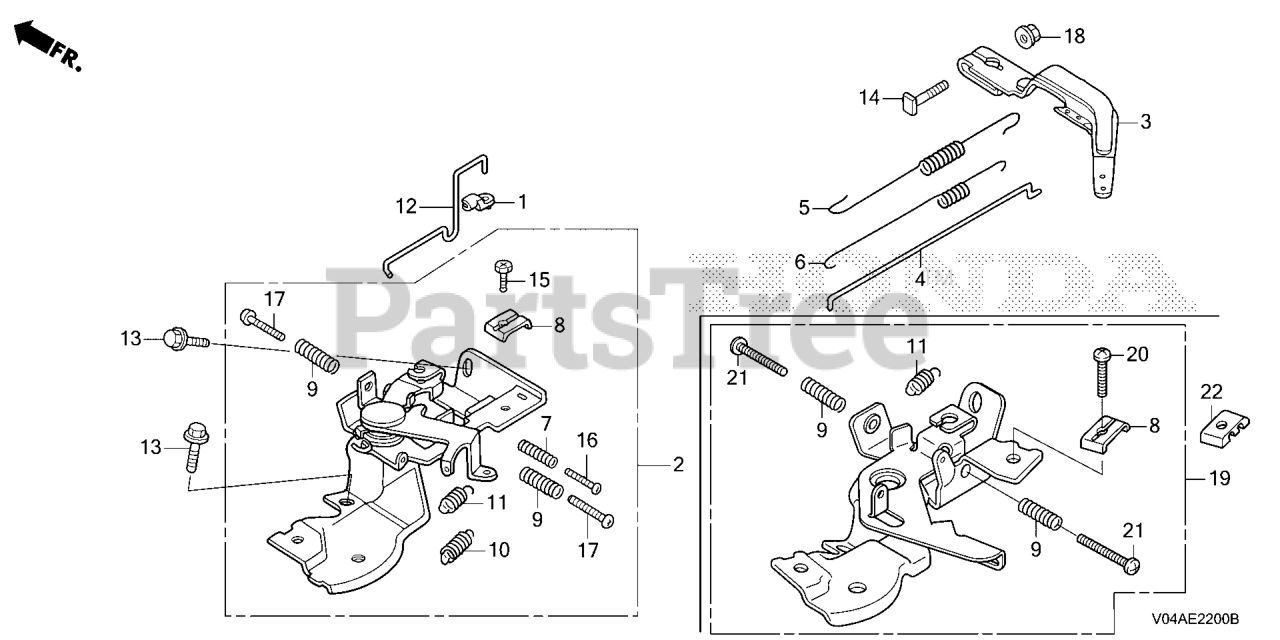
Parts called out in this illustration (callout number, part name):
3	ARM, GOVERNOR
4	ROD, GOVERNOR
5	SPRING, GOVERNOR
6	SPRING, THROTTLE RETURN
8	HOLDER, CABLE
9	SPRING, CONTROL ADJUSTING Use from Engine SN 2327377.
11	SPRING, CABLE RETURN
13	BOLT, FLANGE (6X12) (CT200)
14	BOLT, GOVERNOR ARM
18	NUT, FLANGE (6MM)
19	CONTROL ASSY. (HS)
20	BOLT, RECESSED (5X16)
20	SCREW, PAN (5X16)
21	SCREW, PAN (5X25)
22	HOLDER, CABLE
